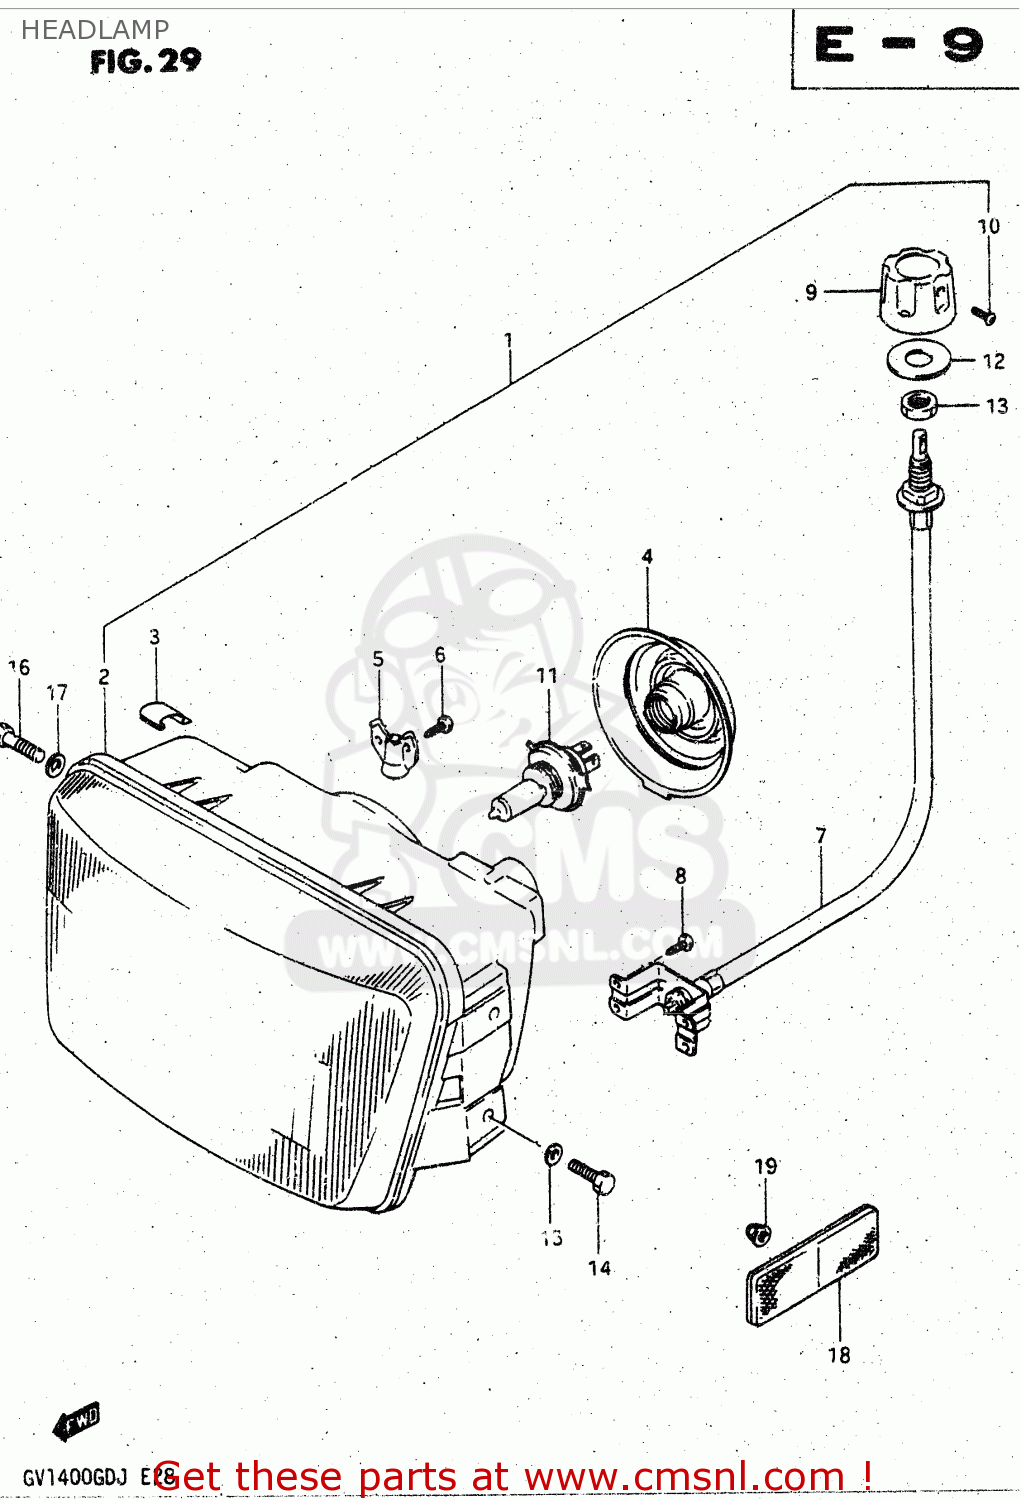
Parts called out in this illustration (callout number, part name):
1	HEADLAMP ASSY
2	LAMP UNIT
3	PLATE,HOOK
4	COVER,SOCKET
5	HOLDER
6	SCREW
7	CABLE,ADJUSTING
8	SCREW
9	KNOB,ADJUSTING
10	SCREW 3X12
11	BULB(12V60/55W,H4)
12	WASHER(12.5X32X2.3)
13	NUT
14	BOLT
15	WASHER,LOCK
16	BOLT ,6X35
17	WASHER, LOWER
18	REFLEX REFLECTOR ASSY,FR SIDE
19	NUT 5MM
